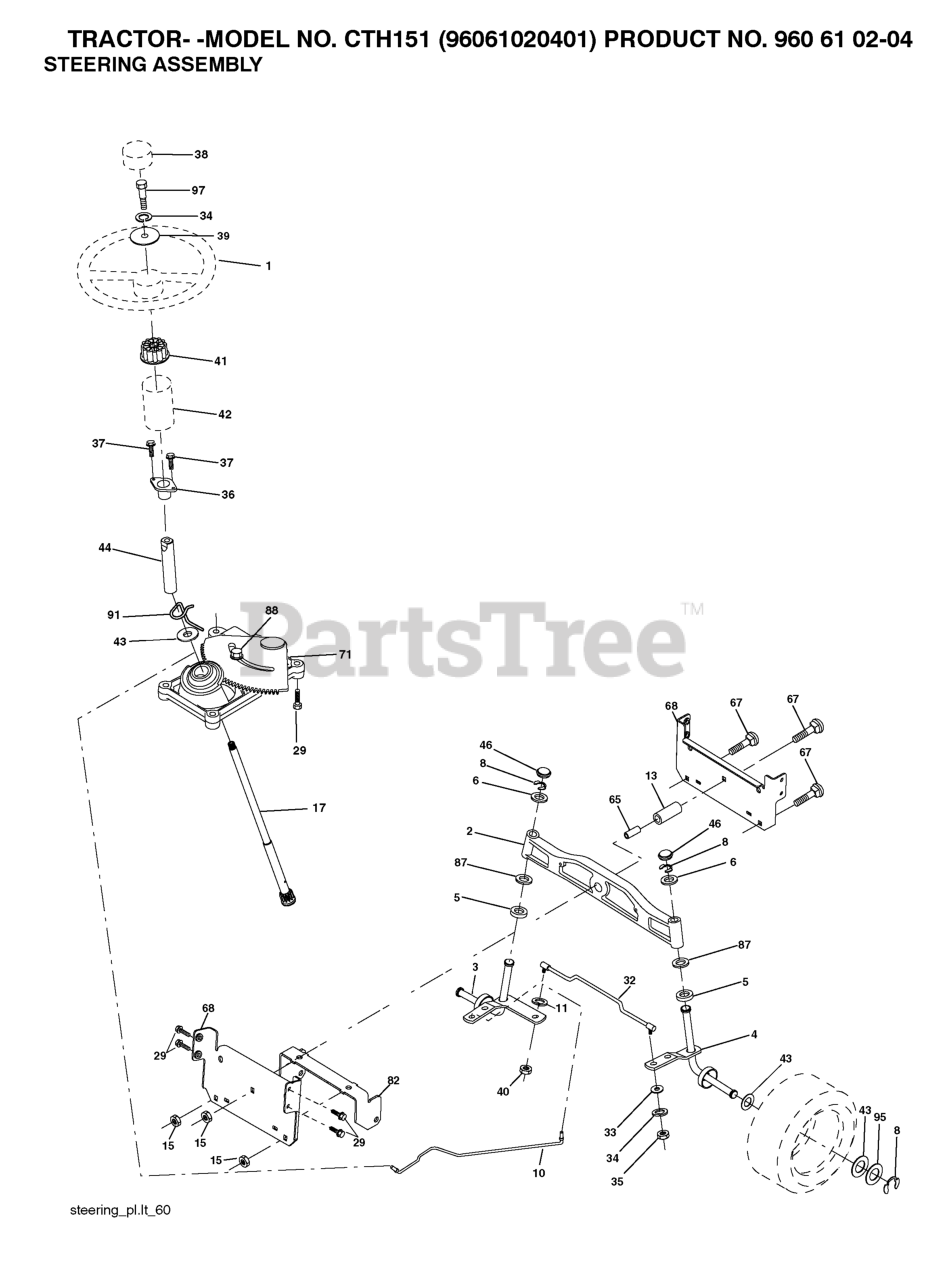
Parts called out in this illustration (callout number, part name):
1	STEERING WHEEL
2	AXLE ASSY FRONT
3	SPINDLE.ASM.LH.15"TIRES
4	SPINDLE.ASM.RH.15"TIRES
5	THRUST WASHER
10	DRAGLINK.15".TIRES.2001
11	WASHER, LOCK 3/8
13	TUBE, PIVOT AXLE
15	NUT
17	SHAFT STEERING SPLINE
29	SCREW, 3/8-16X3/4
33	WASHER M
34	WASHER.LOCK.HVY.HLCL.SPR.5/16
35	NUT, CROWNLOCK
36	BUSHING, STEERING
37	SCREW.TT.#10-32X.5.3/8.FLANGE
38	INSERT.CAP.STRG.WH.GRAY
39	WASHER.11/32
40	NUT CROWNLOCK 3/8-24
41	ADAPTER, WHEEL STNG..
42	BOOT, STEERING
44	SHAFT.EXTEN.STRG.SPLINE
46	CAP.SPINDLE.BLACK
65	SPACER BRACE AXLE
67	BOLT CARRIAGE
68	BRACE.AXLE.15"TIRES
71	STEERING ASM
82	BRACKET.SUSP.CHASSIS.FRONT.15
87	WASHER, FLAT .781 X 1 1/2"
88	BOLT, SHOULDER 7/16-20
91	CLIP.STEERING
95	WASHER.HARDENED
